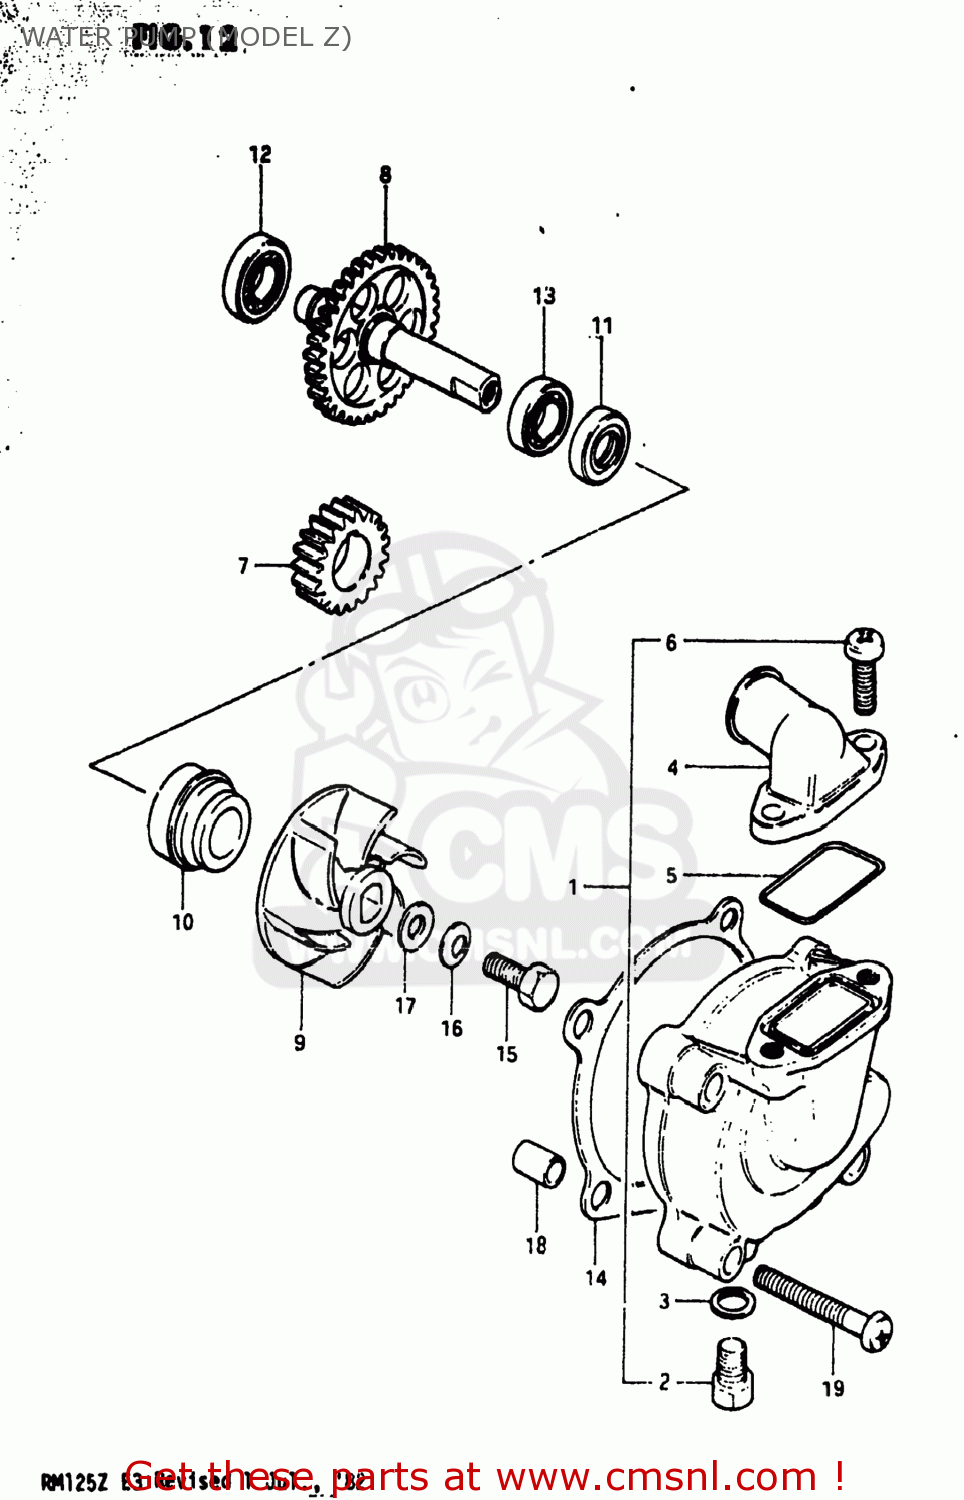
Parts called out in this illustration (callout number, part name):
1	CASE,WATER PUMP
2	BOLT,DRAIN
3	GASKET,DRAIN (NAS)
4	CONNECTOR
5	O RING,WATER PUMP CONNECTOR
6	SCREW
7	GEAR,WATER PUMP DRIVE
8	GEAR,WATER PUMP DRIVEN(NT:36)
9	IMPELLER,WATER PUMP
10	SEAL,WATER PUMP SHAFT
11	SEAL,OIL(10X21X5)
12	BEARING(10X22X6)
13	BEARING
14	GASKET,WATER PUMP CASE (MCA)
15	BOLT(6X13)
16	WASHER
17	GASKET (NAS)
18	PIN
19	SCREW
